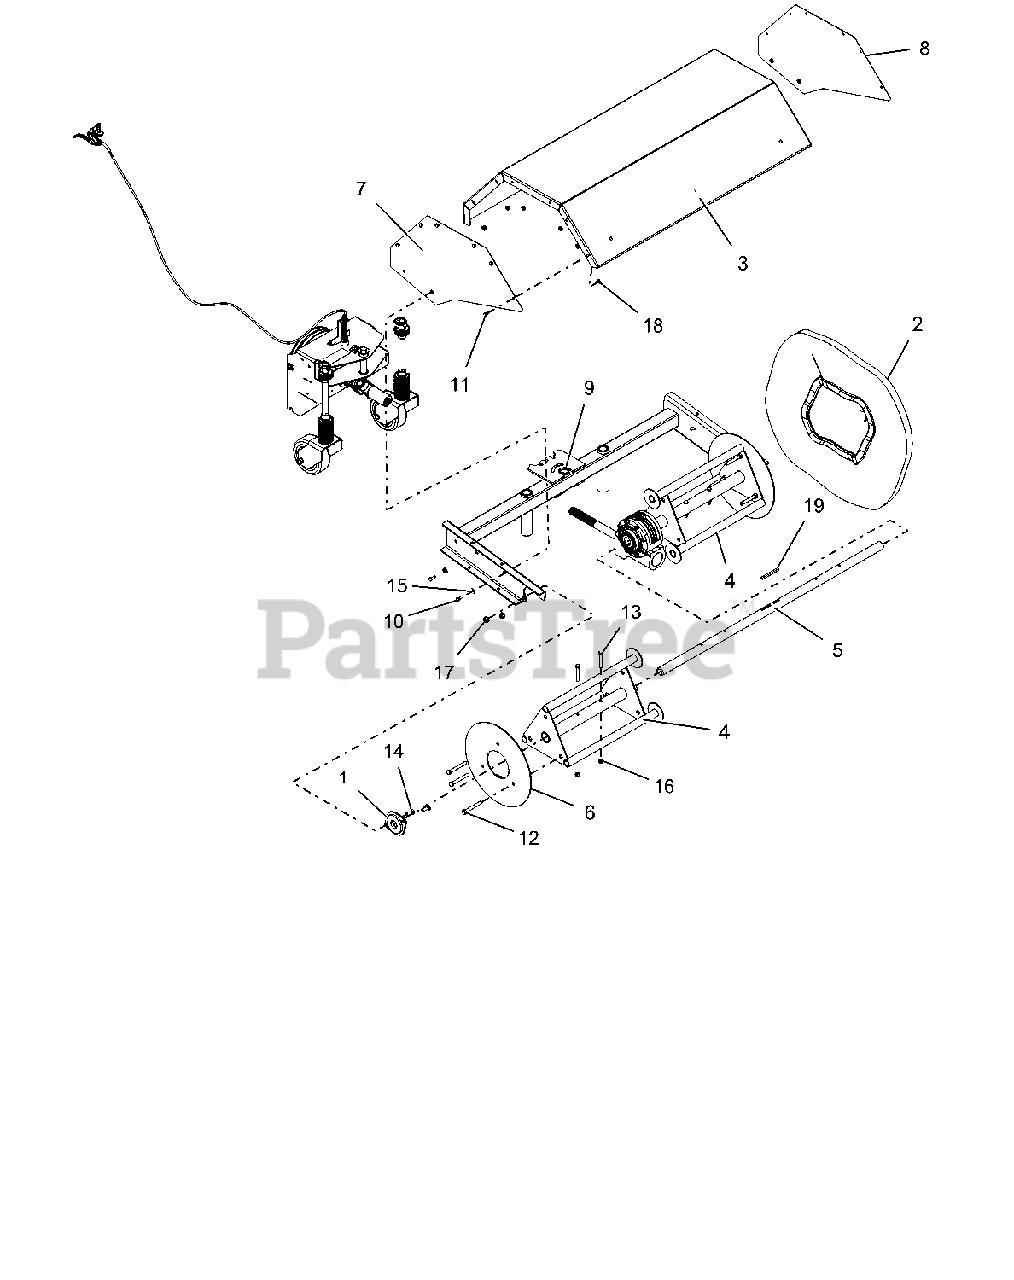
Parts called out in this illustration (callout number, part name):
1	BEARING,2 BOLT FLANGE 1-1/8 ID
2	KIT, BRISTLE - SET OF 18
3	COVER, TOP - 36" BRUSH W/DECAL
4	PB36 DRIVE CORE SERVICE KIT
5	CENTER, SHAFT
6	PLATE, END RETAINER
7	WLDT, SIDE COVER - RH
8	WLDT, SIDE COVER - LH
9	FRAME, POWER BROOM 36"
10	@BLT-HEX .25-20X.75 GR5 YWZC
11	@BLT-HEX .25-20X.50 GR5 YWZC
12	BLT-HEX .38-16X3.00 GR5 FTH YZ
13	@BLT-HEX .31-18X2.25 GR5 YWZC
14	@BLT-RDHDSQNK .38-16X1.00 G5YZ
15	@WSHR-FL-STL.312X.734X.065 YWZ
16	@NUT-LK-CTR .31-18 YWZC
17	@NUT-LK-TOP-FLG .38-16 YWZC
18	@NUT-LK-TOP-FLG .25-20 YWZC
19	KEY .25 X .25 X 3IN
